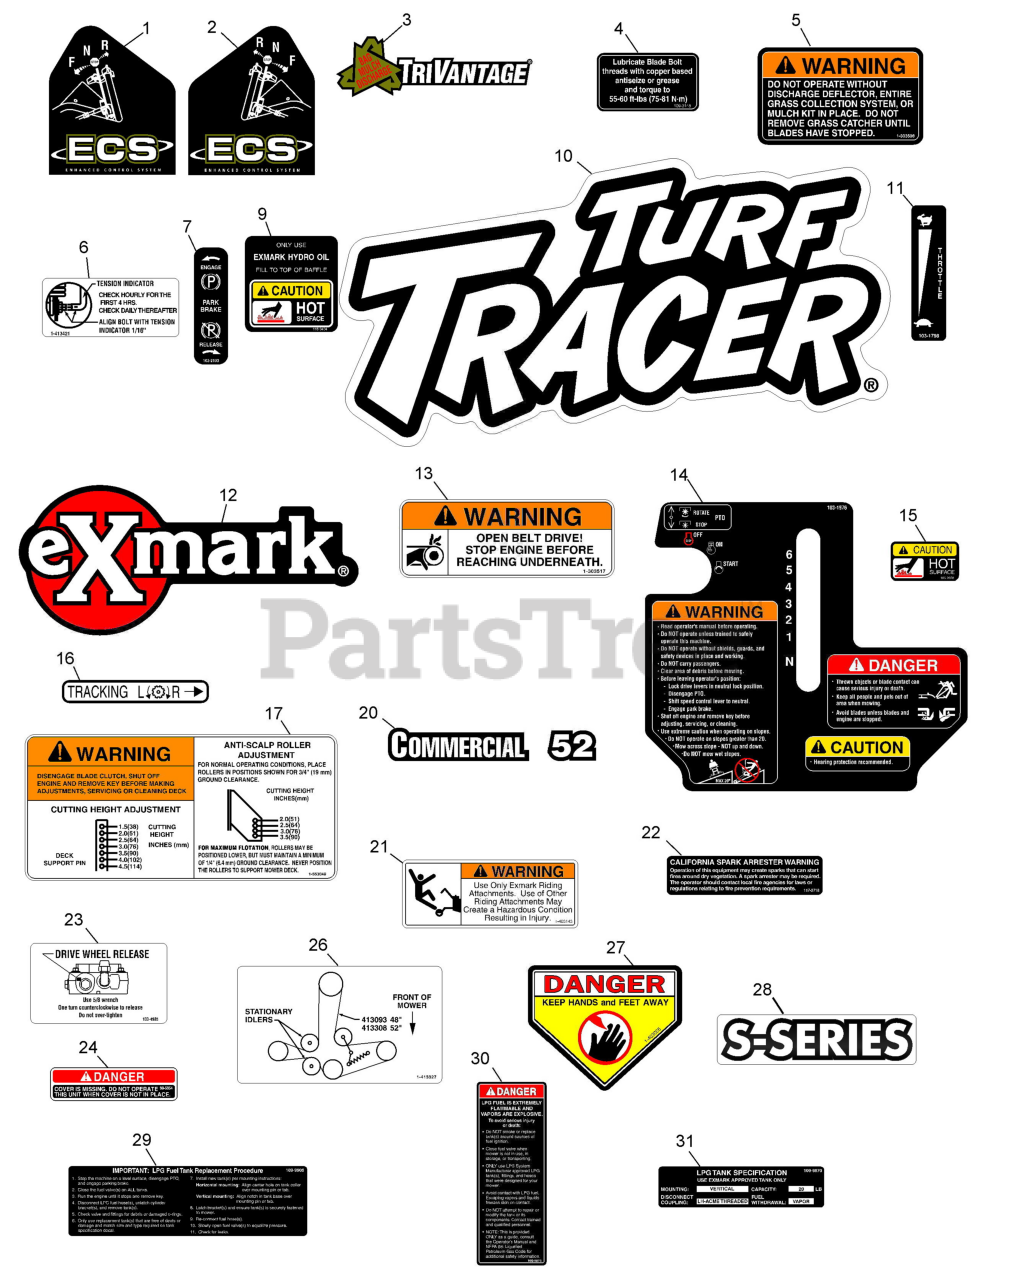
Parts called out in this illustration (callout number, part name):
1	DECAL,LH ECS INSTRUCTION
2	DECAL,RH ECS INSTRUCTION
4	DECAL,BOLT TORQUE
5	DECAL-WARNING, DISCHARGE
6	DECAL,INDICATOR
7	DECAL-BRAKE, PARK
9	DECAL-HYDRAULIC TANK
10	DECAL,TTH MODEL
11	DECAL,THROTTLE ONLY
12	DECAL,EXMARK LOGO
13	DECAL,BELT DRIVE
14	DECAL,CONSOLE
15	DECAL-CAUTION
16	DECAL,TRACKING ADJUST
17	DECAL,ANTI SCALP
20	DECAL,COMMERCIAL 52
21	DECAL,SULKY WARNING
22	DECAL-ARRESTER, SPARK
23	DECAL,DRIVE RELEASE
24	DECAL-COVER, MISSING
26	DECAL,BELT ROUTING
27	DECAL-DANGER
28	DECAL-S-SERIES
29	DECAL-TANK REPLACEMENT
30	DECAL-LPG WARNING
31	DECAL,LPG TANK SPEC VERTI
